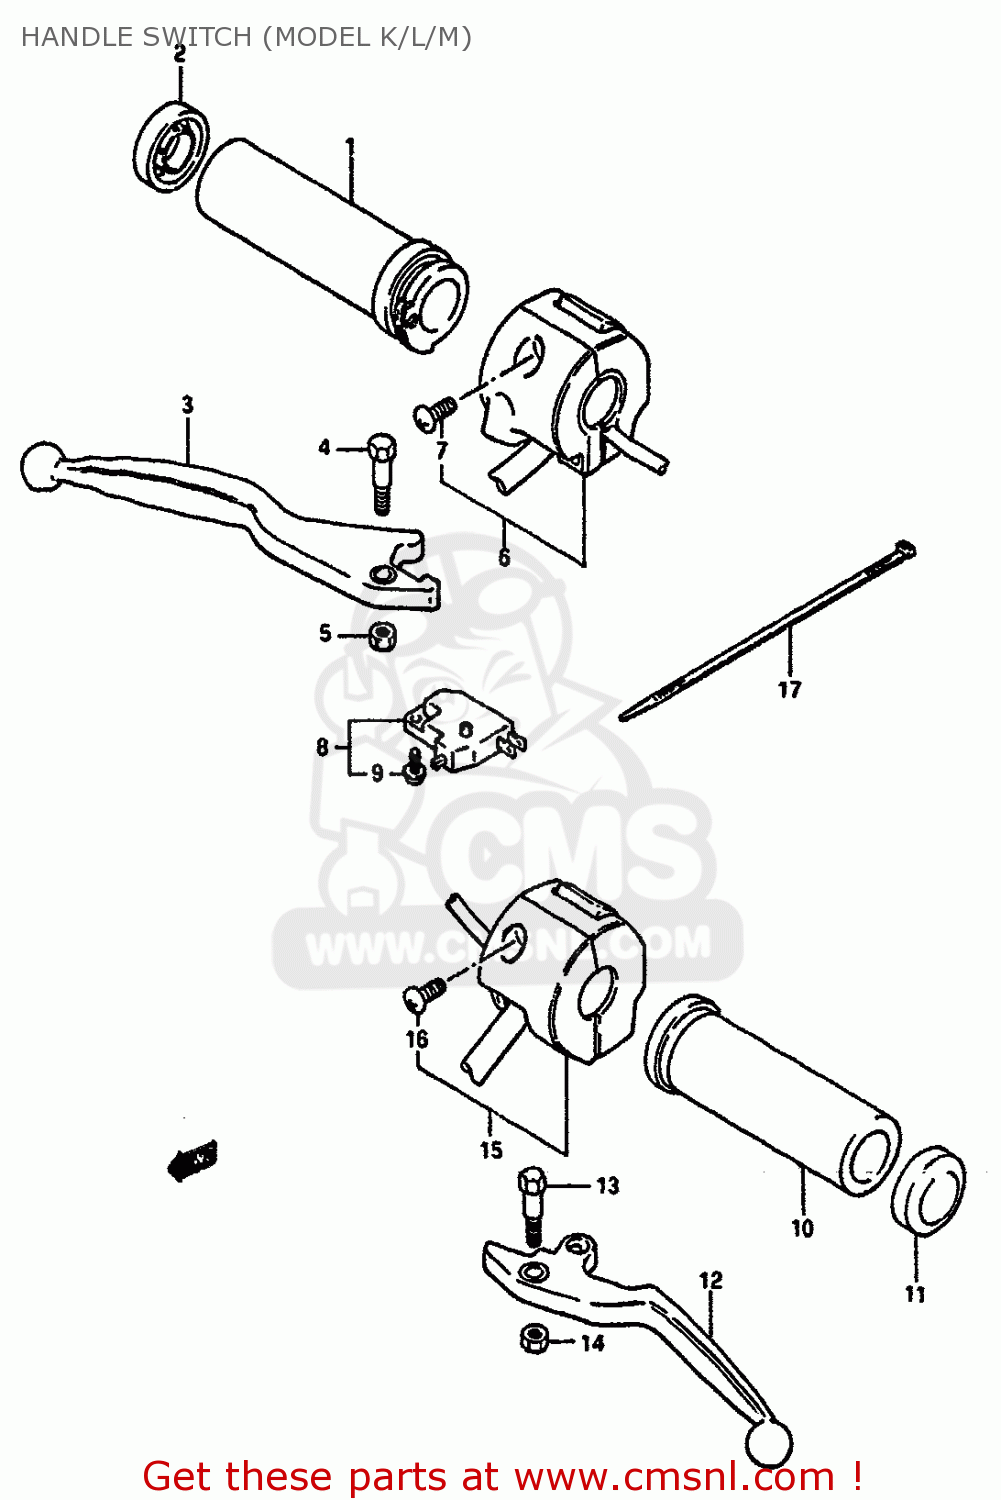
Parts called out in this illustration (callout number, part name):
1	GRIP,THROTTLE
2	CAP,GRIP END
3	LEVER,BRAKE
4	BOLT,LEVER
5	NUT 6MM
6	SWITCH ASSY,HA
7	SCREW
8	SWITCH ASSEMBLY,STOP
9	SCREW
10	GRIP,L
11	CAP,GRIP END
12	LEVER,CLUTCH (SILVER)
13	BOLT,LEVER
14	NUT 6MM
15	NUT 6MM
16	SWITCH ASSY,HANDLE LH (PULL BACK TYPE)
17	CLAMP
18	CLAMP
